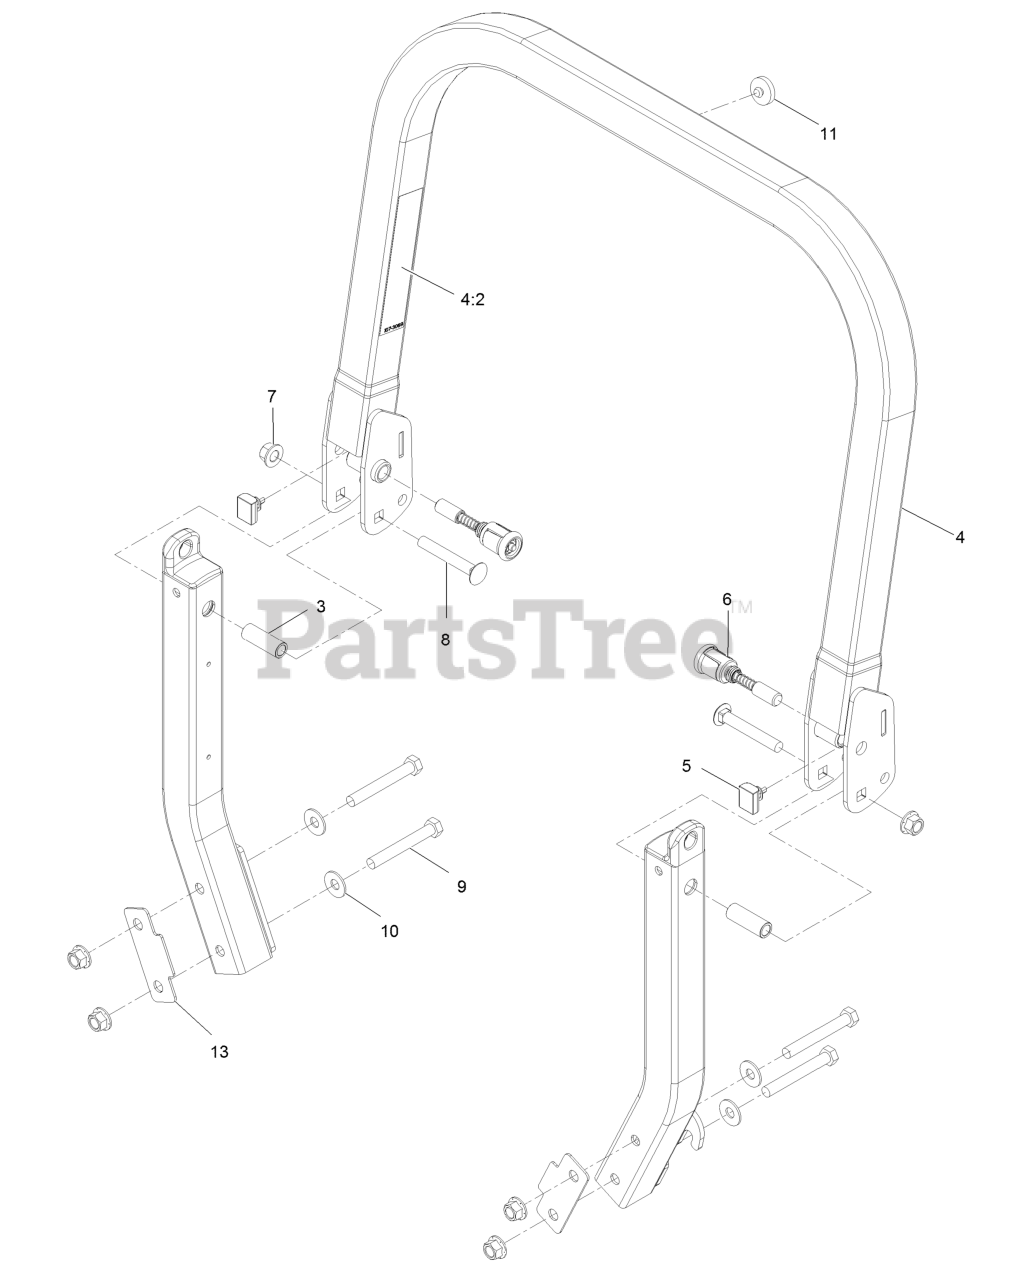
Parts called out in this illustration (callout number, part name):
4	Upper ROPS ASM
4:2	Decal-Warning
5	Bumper-ROPS
6	Pin-Spring
7	Nut-Lock 1/2-13
8	Bolt-Carriage 1/2-13 X 3 1/2
9	Screw-HH
10	Washer, Spring Disc 1/2
11	Bumper-Push-In, Rubber
